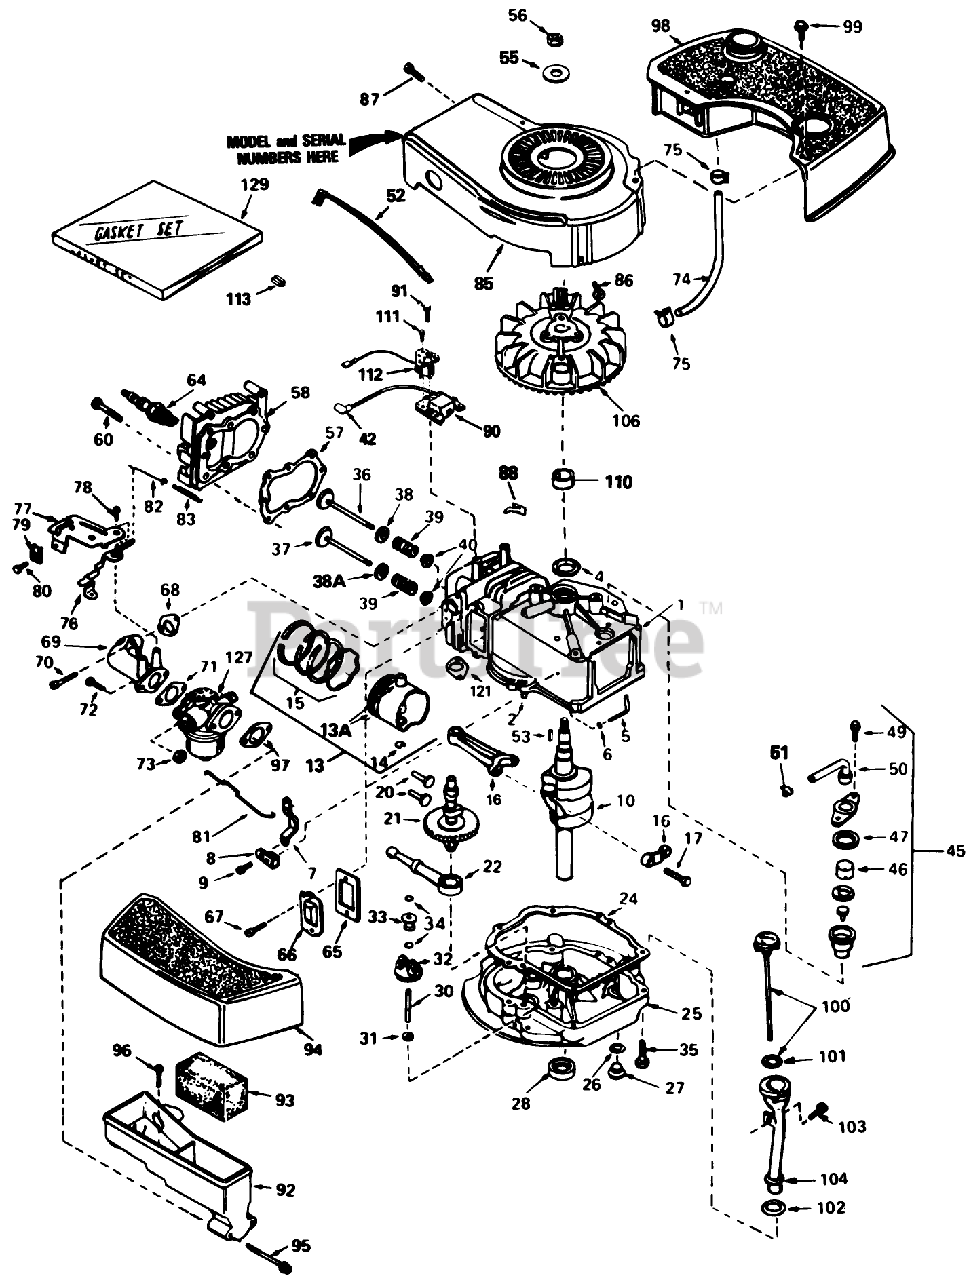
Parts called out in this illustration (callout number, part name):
1	Cylinder Assy. (Inc. #2 4)
2	Pin-Dowel
4	Seal-Oil
5	Rod, Governor (Incl. No. 36)
6	Washer-Flat
7	Governor Lever
8	Clamp-Lever, Governor
9	Screw
10	Crankshaft
13	Piston, Pin Ring Assy. (Std.) (Incl. Ref. #13A, 14 15)
13	Piston, Pin Ring Assy. (.010 oversize) (Incl. Ref. #13A, 14 15)
13	Piston, Pin Ring Assy. (.020 oversize) (Incl. Ref. #13A, 14 15)
13A	Piston Pin Assy. (Incl . Ref. . #14) (Std.)
13A	Piston Pin Assy. (Incl. Ref. #14) (.010 Oversize)
13A	Piston Pin Assy. (.020 oversize) (Incl. Ref. #14)
14	Ring-Retaining, Piston Pin
15	Ring Set (Std.)
15	Ring Set (.020" OS)
15	Ring Set (.010" OS)
16	Rod Assy., Connecting (Incl. Ref. #17)
17	OA Bolt-Connecting Rod
20	Lifter-Valve
21	Camshaft(Mech.Comp. Release)
22	Oil Pump ASM
24	Gasket
25	Flange Assy.-Mounting (Incl. Ref. #26, 27, 28 31)
26	Gasket-Oil Drain
27	Plug Oil Drain
28	Seal Oil
30	Shaft-Governor
31	Washer-Flat
32	Governor Gear ASM
33	Spool-Governor
34	Ring-Retaining
35	Screw (1/4-20 x 1-1/4)
36	Valve, Intake (Std.) (Incl. Ref. #40)
36	Valve, Intake (1/32" oversize)(Incl. No. 40)
37	Valve, Exhaust (Std.)(Incl. No. 40)
37	Valve, Intake (1/32" oversize)(Incl. No. 40)
38	Seal Assy., Intake
38A	Cap-Upper Valve Spring
39	Spring-Valve
40	Cap-Valve, Spring
42	Cover-Spark Plug
45	Breather Assy. (Incl. Ref. #46 thru 51)
46	Element-Breather
47	Gasket-Breather
49	Screw (10-24 x 9/16)
50	Tube, Breaker
51	Clip, Breather
52	Wire-Ground
53	Key-Flywheel
55	Washer-Belleville
56	Nut-Flywheel
57	63573 GIL 42 SNWTHW
58	Head-Cylinder
60	Screw (5/16-18x1-1/2)
64	Plug, Spark (Autolite 458, Champion J-19LM or equiv.)
65	Gasket-Breather
66	Cover-Valve
67	Screw
68	Gasket-Intake
69	Pipe, Intake (Incl. No. 68)
70	Screw (1/4-20 x 1)
71	Gasket-Carburetor
73	Nut and Lock Washer (1/4-28)
74	Line-Fuel
75	Clamp-Line, Fuel
76	Lever Control
77	Control Assy., Speed (Incl. Nos, 76, 78 89)
78	Screw, Hex Washer Hd Shoulder Self-Tap
79	Conduit
80	Screw (10-32 x 3/8)
81	Link-Throttle
82	Link Governor Spring
83	Spring Governor
85	Housing-Blower
86	Screw (1/4-20x19/32)
87	Screw (10-24 x 9/16)
88	Clip-Wire
90	Solid State
91	Screw
92	Body Air Cleaner
93	Filer, Air
94	Cove, Air Cleaner
95	Screw Fil Hd.
96	Screw, Hex Washer Hd Shoulder Self-Tap
97	Gasket-Air Cleaner
98	Tank-Fuel
99	Screw (10-32 x 35/64)
100	Dipstick, Oil (Incl. Ref. #101)(Twist Lock)
101	O-Ring
102	Gasket
103	Screw (10-32 x 1/2)
104	Tube-Oil Fill
106	Flywheel
110	Spacer
111	Screw (8-32x27/64)
112	Coil, Alternator
113	Connector-Body
121	Gasket Exhaust
127	Carburetor (Incl. Ref. #71)
129	Gasket Set
